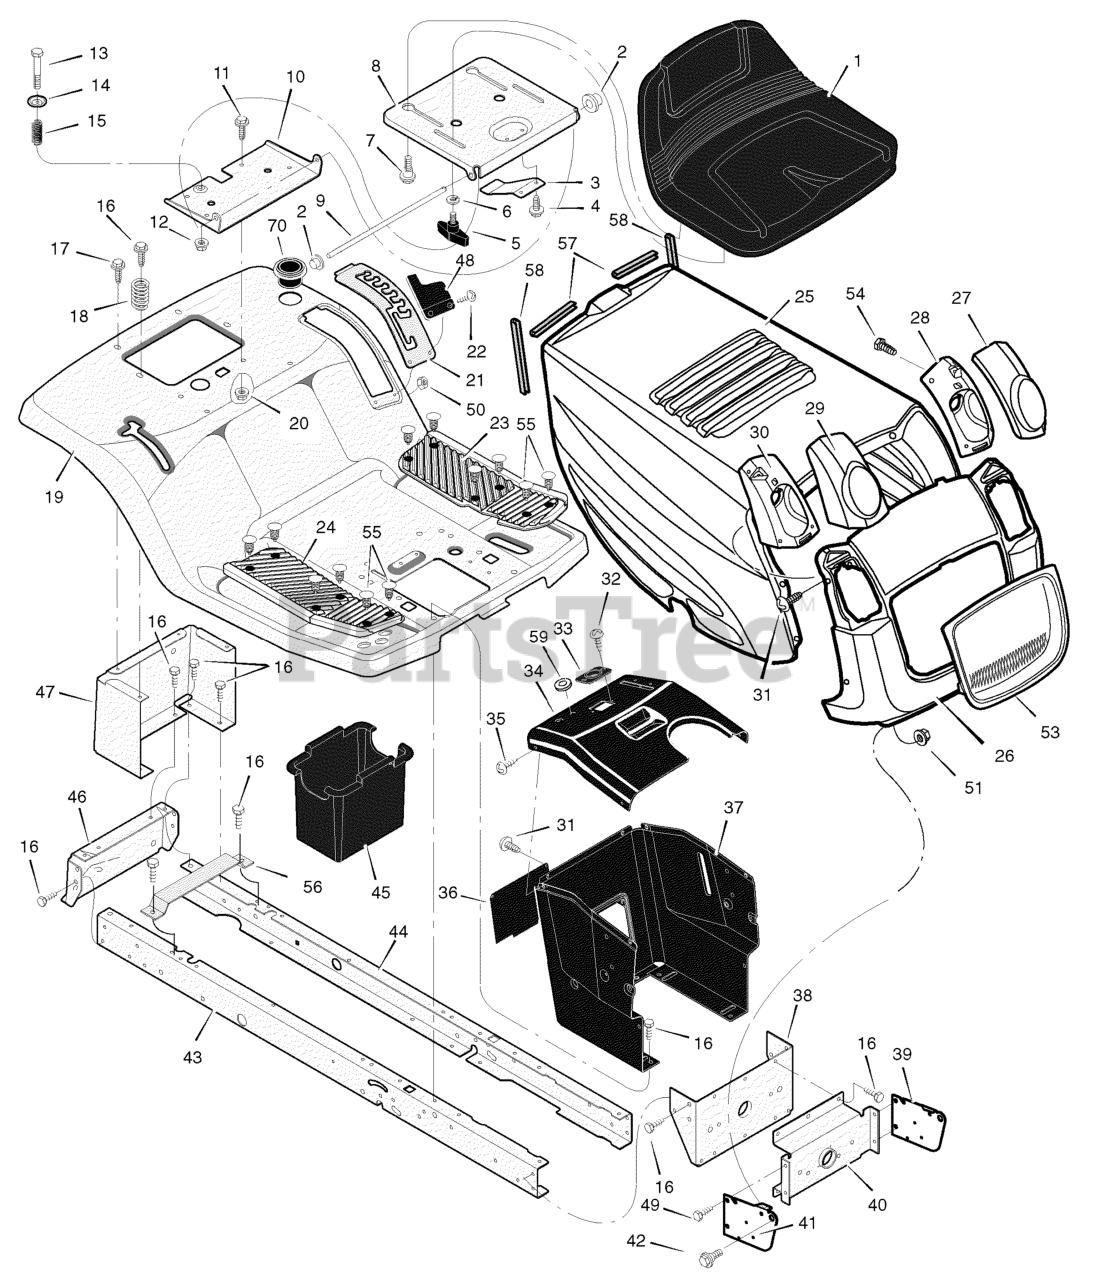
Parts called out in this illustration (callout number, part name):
2	Cap, Push 0n
3	Spring
4	Screw
5	Bolt, Wing
6	Washer
7	Bolt, Shoulder
8	Support, Seat
9	Rod, Pivot
10	Bracket, Pivot
11	Bolt
12	Nut
13	Bolt, Shoulder
15	Spring
16	Screw
17	Screw
18	Spring
19	Deck, Seat
20	Nut
21	Plate, Index
22	Screw
23	Mat, Left
24	Mat, Right
27	Lens, Left
28	Housing, Left Headlamp
29	Lens, Right
30	Housing, Right Headlamp
31	Screw
33	Bearing, Steering
35	Screw
36	Panel, Access
37	Support, Dash
38	Bracket, Rear Hanger
39	Support, Left Grille
40	Axle, Hanger
41	Support, Right Grille
42	Bolt, Shoulder
43	Frame, Right
44	Frame, Left
45	Container, Battery
46	Plate, Hitch
47	Panel, Rear
48	Cover, Detent
49	Screw
50	Nut
53	Insert, Grille
55	Fastener, Panel
56	Support, Battery
57	Trim, Hood (3.75")
58	Trim, Hood (6.5")
59	Grommet, Parking Brake
70	Holder, Cup
